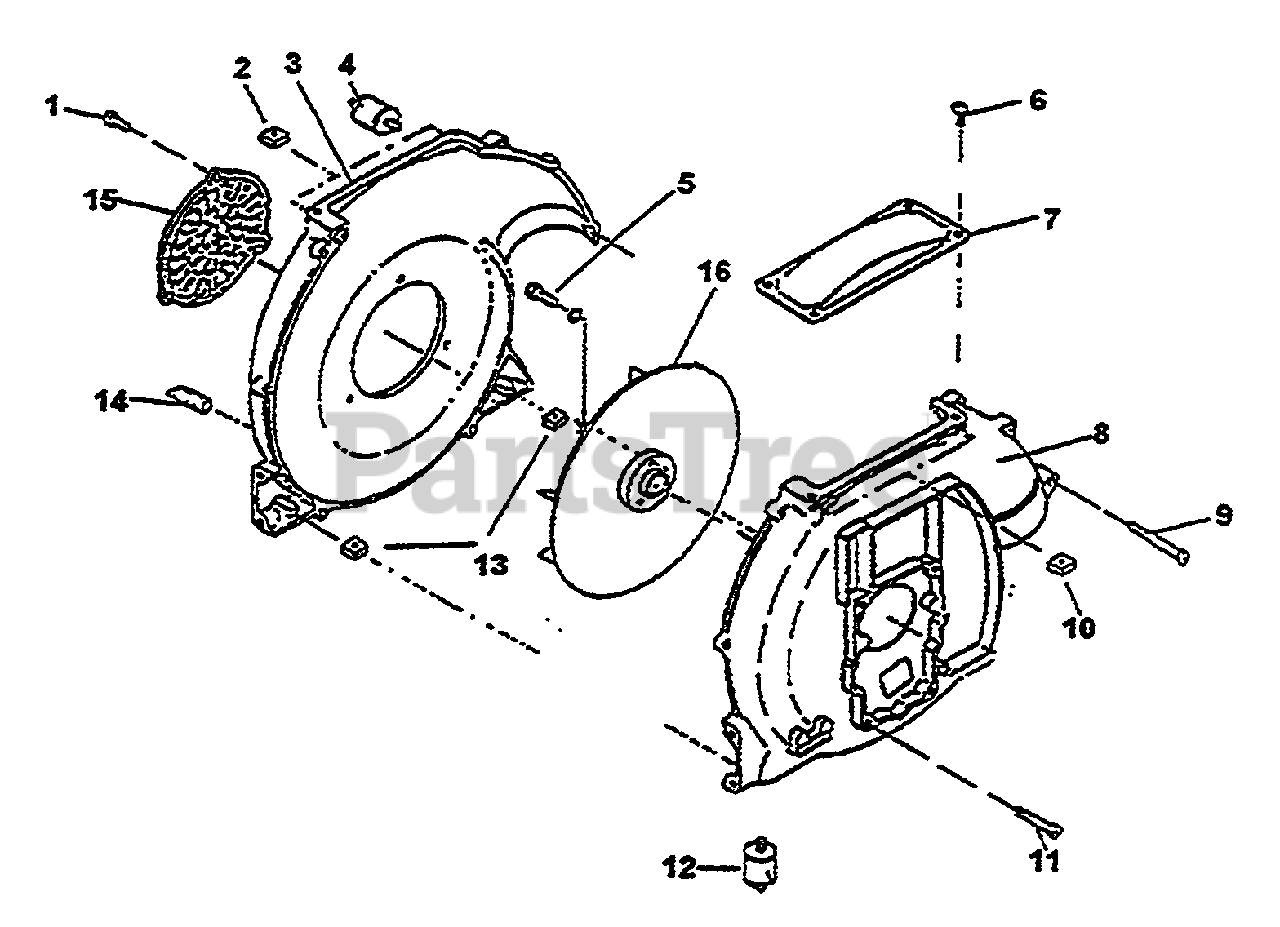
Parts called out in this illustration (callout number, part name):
3	FAN CASE, FRONT
4	ANTI-VIBE INSULATOR
8	FAN CASE, REAR
12	ANTI-VIBE INSULATOR
15	FAN COVER
